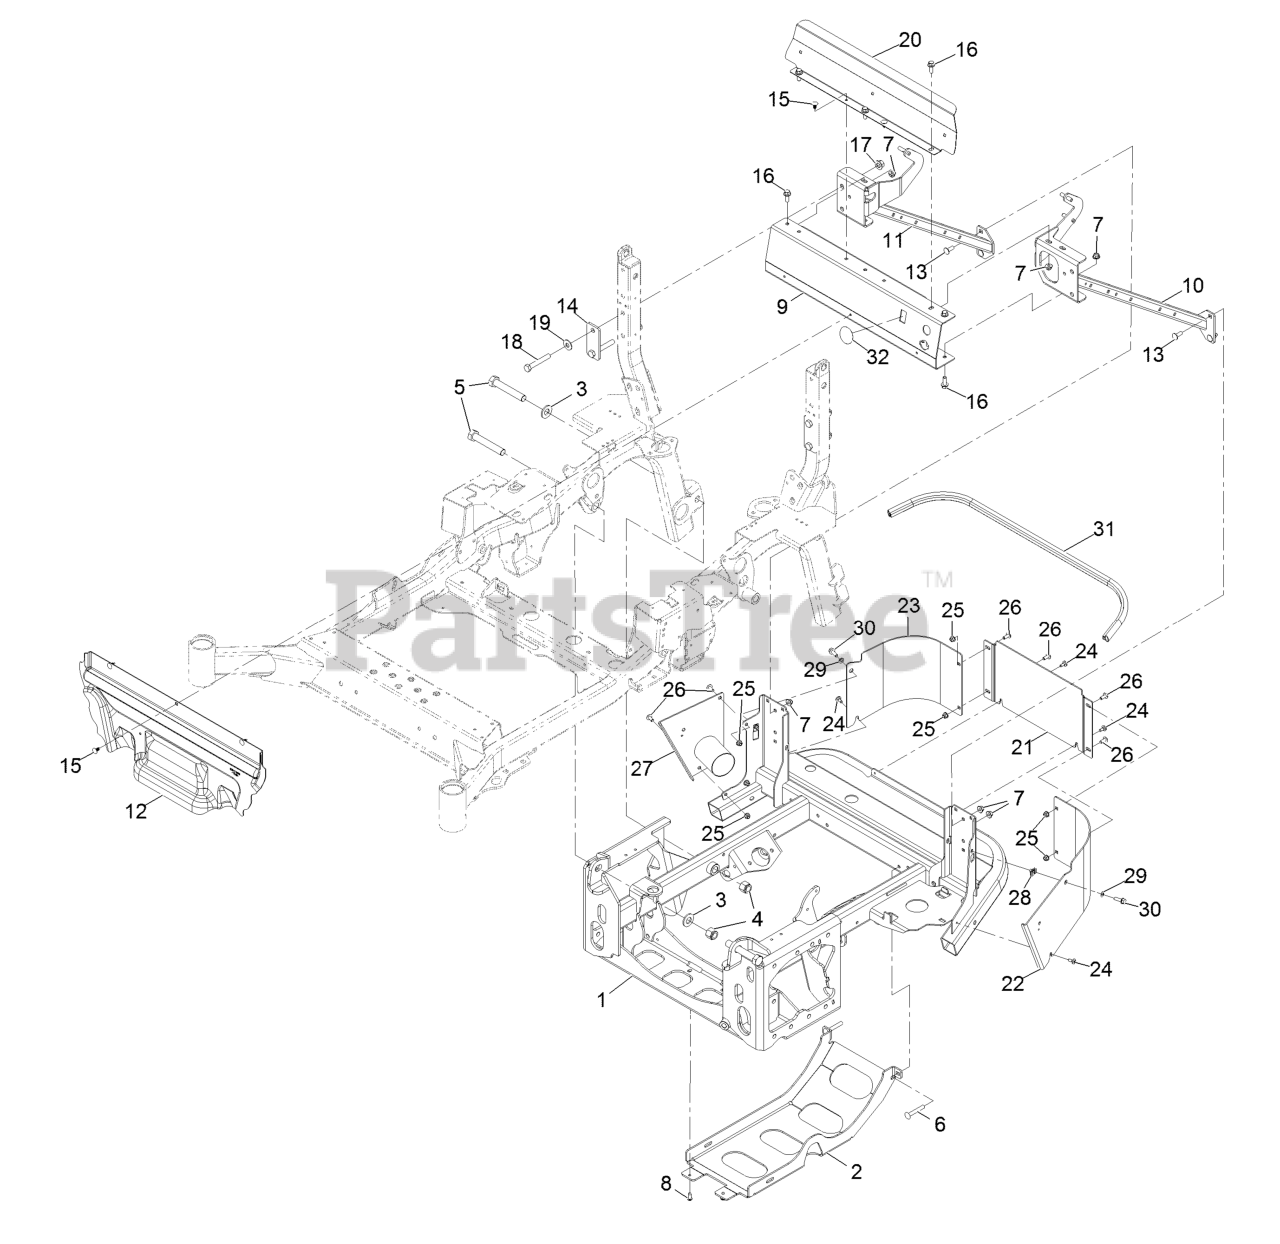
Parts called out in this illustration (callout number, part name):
1	Frame-Power
2	Plate-Skid
3	Washer-Spring Disc 3/4
4	Nut-Nyloc 3/4-10
5	Screw-HH
6	Bolt-Carriage 3/8-16 X 2 1/2
7	Nut-Nyloc 3/8-16 Flg
8	Screw-Button Head 5/16-18 X .725 Tf
9	Channel-Cross
10	Brace-ROPS, LH
11	Brace-ROPS, RH
12	Panel-Deflector, Heat
13	Bolt-Carriage 3/8-16 X 1
14	Plate-Spacer
15	Plug-Plastic
16	Screw-HHF
17	Nut-Lock 1/2-13
18	Screw-HH
19	Washer, Spring Disc 1/2
20	Shield-Air
21	Plate-Bumper, Center
22	Plate-Bumper, LH
23	Plate-Bumper, RH
24	Screw-1/4-20 X 1/2 Tf Torx Plus
25	Nut-Nyloc 5/16-18 Flg
26	Screw-Truss HD 5/16-18 X 3/4 Torx Plus
27	Plate-Exhaust
29	Washer-Belleville
30	Screw-HH Flg 5/16-18 X 1
31	Seal-Bulb
32	Decal-Cover
